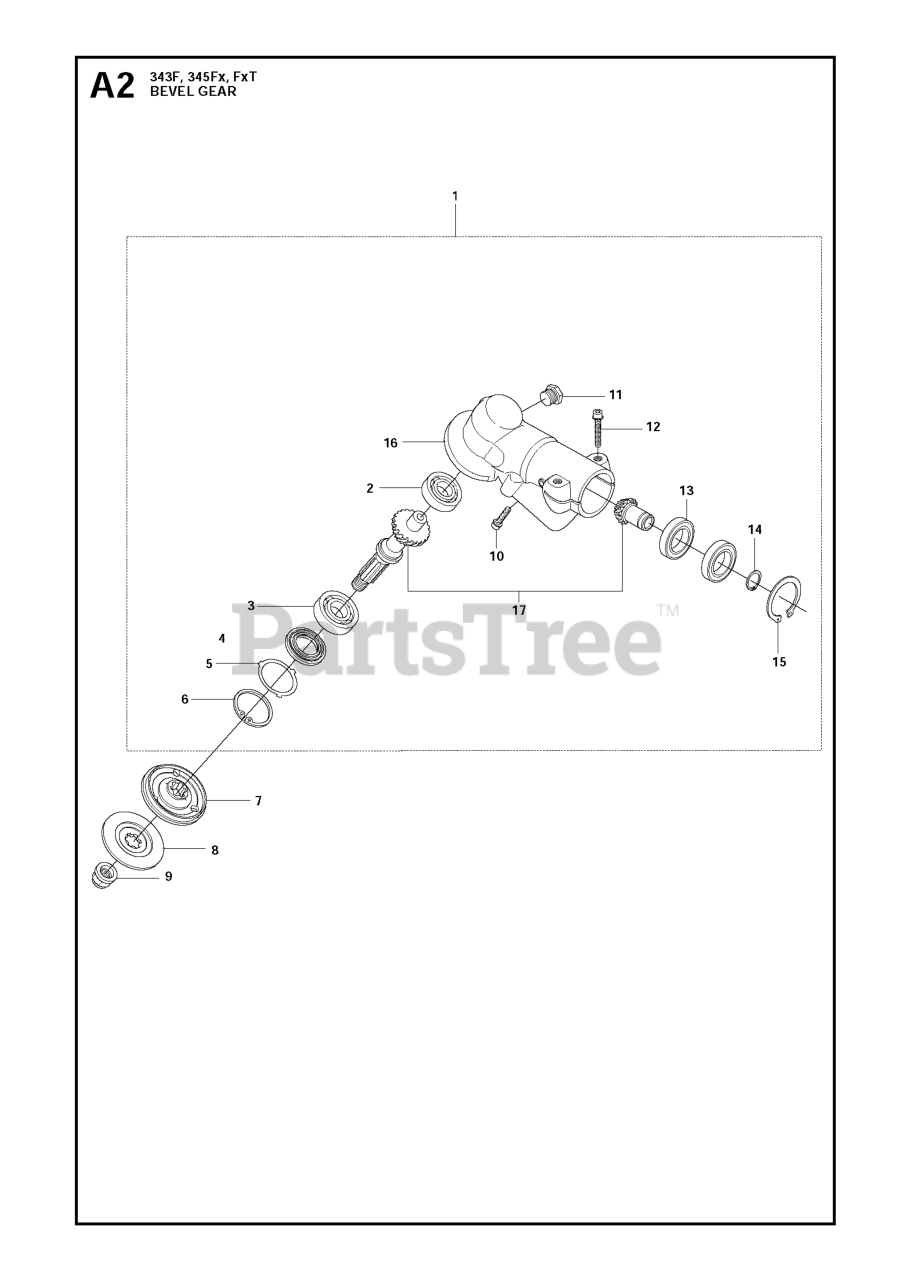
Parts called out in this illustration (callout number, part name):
1	RP_GEAR HOUSING ASSY
2	BALL BEARING
3	BALL BEARING
6	RETAINING RING SGH 35
7	DRIVER
8	SUPPORT FLANGE
13	BALL BEARING
14	RETAINING RING SGA 15
15	RETAINING RING
16	GEAR HOUSING
17	RP_SPARE PARTS KIT
